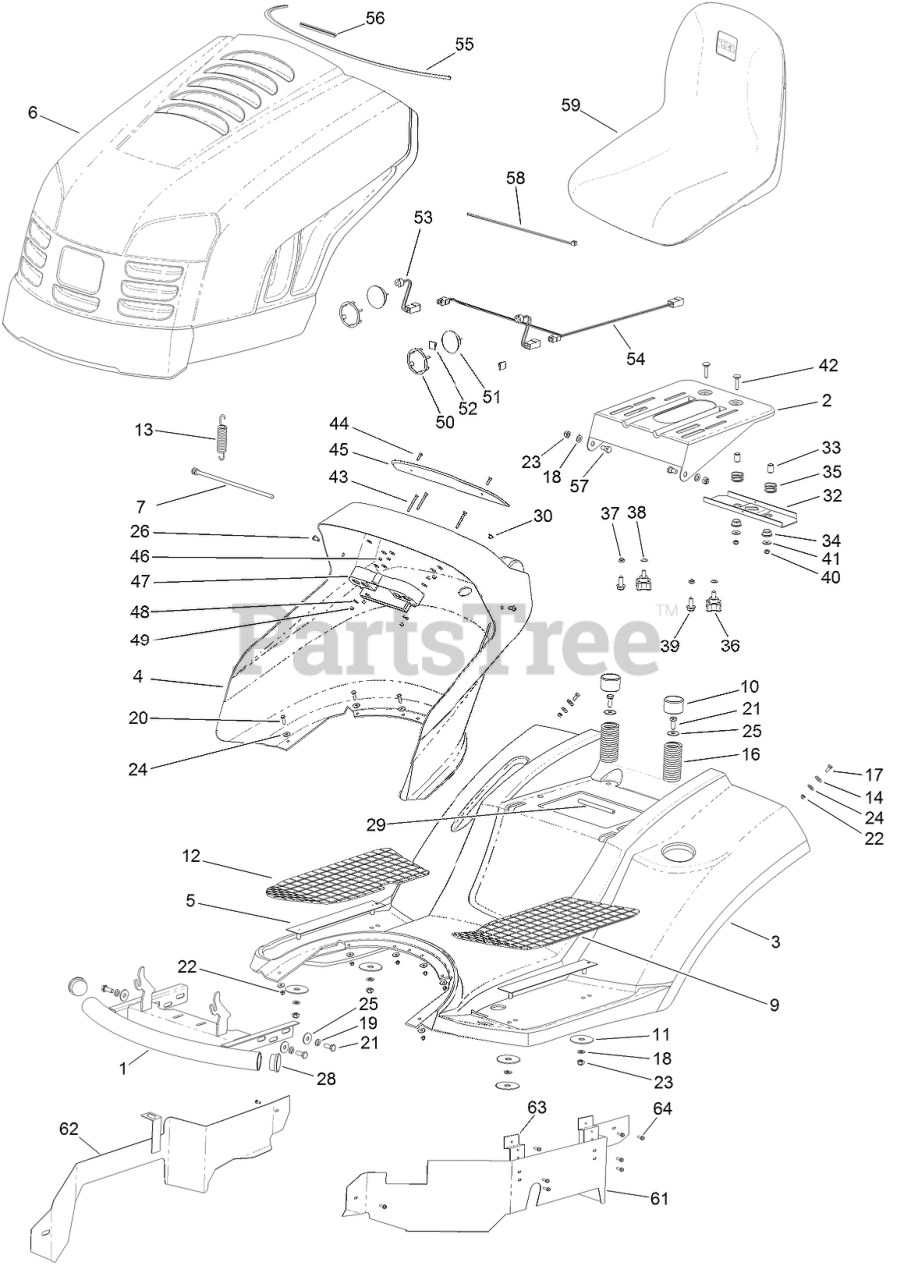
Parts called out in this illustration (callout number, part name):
1	BUMPER
2	BRACKET-SUPPORT, SEAT
3	FENDER-REAR
4	PANEL-DASH
5	HOLDER
6	HOOD ASM
7	HOLDER-SPRING
9	MAT-FOOT, LH
10	CAP-HUB
11	WASHER-RUBBER
12	MAT-FOOT, RH
13	SPRING-HOOD
14	WASHER-RUBBER
16	SPRING-SEAT
18	WASHER-PLAIN
19	WASHER-SPRING
21	SCREW-HH
22	NUT-LOCK
23	NUT-LOCK, NI
24	WASHER-FLAT
25	WASHER-PLAIN
26	SCREW-HH
29	TRIM-RUBBER
32	BRACKET
33	SPACER-SPLIT
34	BUSHING
35	SEAT-SPRING
36	KNOB-ADJUST
37	SPACER
38	WASHER-SPRING
39	SCREW-SUPPORT, SEAT
40	NUT-LOCK
41	WASHER-FLAT
42	SCREW-CARR
45	LENS-DASH
47	HOUSING-LIGHT, INDICATOR
48	WASHER
49	NUT-HEX
50	SOCKET-LAMP
51	BULB-LIGHT
52	CLIP-NYLON
53	HARNESS-WIRING, LIGHT BULB
54	HARNESS-WIRING, LIGHT
55	TRIM-RUBBER, HOOD
56	GASKET-FOAM
57	SCREW-SUPPORT, SEAT
58	TIE-CABLE
59	SEAT ASM
61	COVER,-LEFT
62	COVER-RIGHT
63	HOLDER
64	SCREW-TAP
